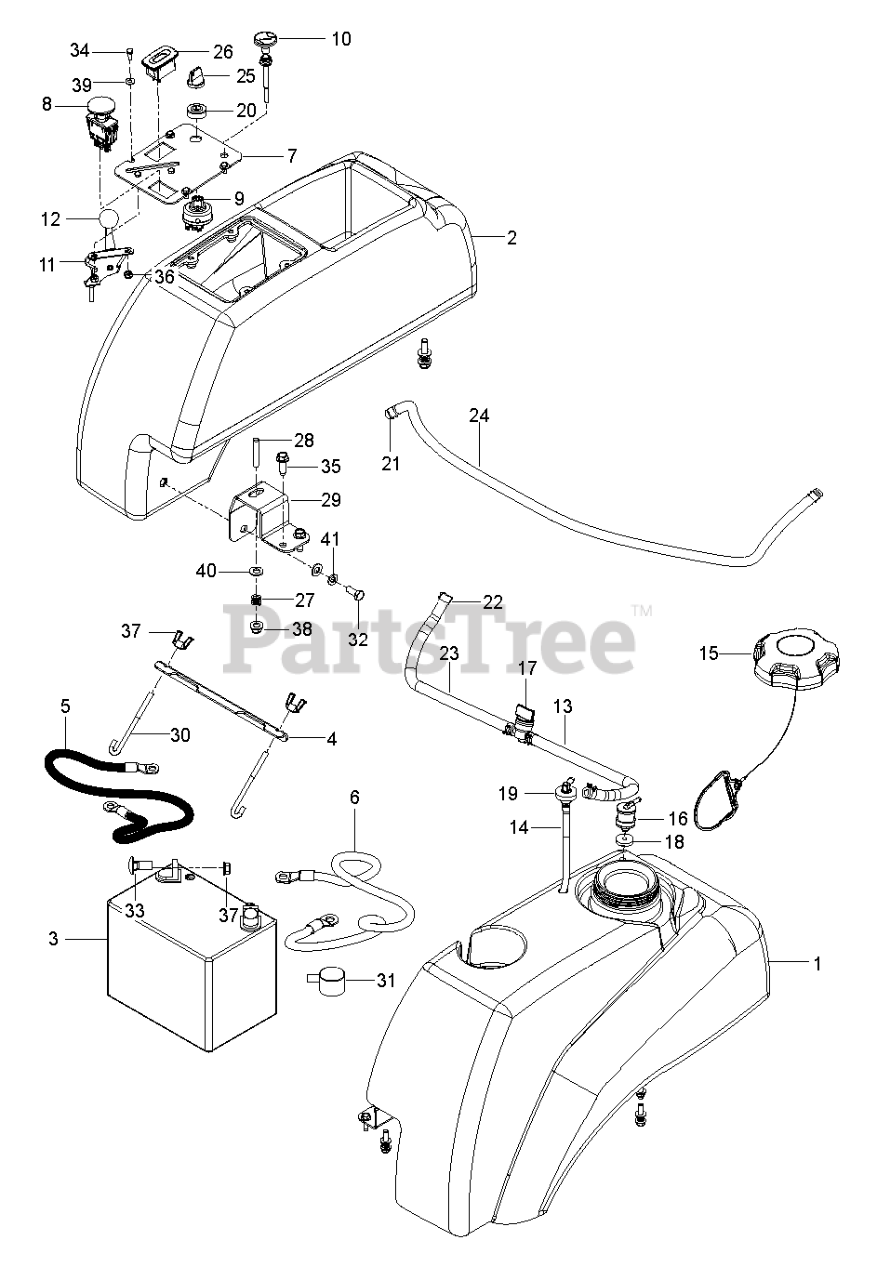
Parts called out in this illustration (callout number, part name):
1	FENDER CONSOLE
2	FUEL.TANK.ASSY.LH.MZ.GRY.17
3	BRACKET.BATTERY.MOUNT.PLATED
4	THROTTLE CABLE
5	CABLE.GROUND.BATT.MZ.BLACK.39"
6	CABLE.BATT.SOLENOID.MZ.RED.25"
7	PLATE.CONSOLE.BLACK
8	RP SWITCH.PTO.TERMINAL.STD.RED
9	SWITCH, IGNITION, INDAK
10	CHOKE CABLE
11	THROTTLE CABLE W/KNOB
12	KNOB.ROUND.BALL.BLACK
13	FUEL.HOSE.SHUT.OFF.ASM.10".10"
14	FITTING, FUEL
15	CAP, FUEL
16	VALVE.FUEL.CHECK
17	FUEL VALVE
18	GROMMET, CHECK VALVE
19	RUBBER GROMMET
20	CAP IGNITION NUT
21	CLAMP, HOSE
22	HOSE CLAMP
23	HOSE.1/4".LOW.PERM.FUEL.LN.10"
24	HOSE.3/16".VAPOR.LINE.27"LGTH
25	KEY, IGNITION
26	GUAGE.SRVCMNDR.HRMTR.
28	STUD, 5/16C
29	SUPPORT.PNT.TANK.FRONT.STAMPED
31	COVER.TERMINAL.BATTERY
32	SCREW HEXAGON HEAD SCREW 5/16-
33	GSPW Bolts
35	SCREW HEX HEAD W/ WASHER 5/16-
37	WING NUT 1/4
38	NUT HEXAGON FLANGE 5/16-18 ST
40	WASHER 11/32 X 11/16 X 14 GA T
41	WASHER SPRING LOCK WASHER WITH
